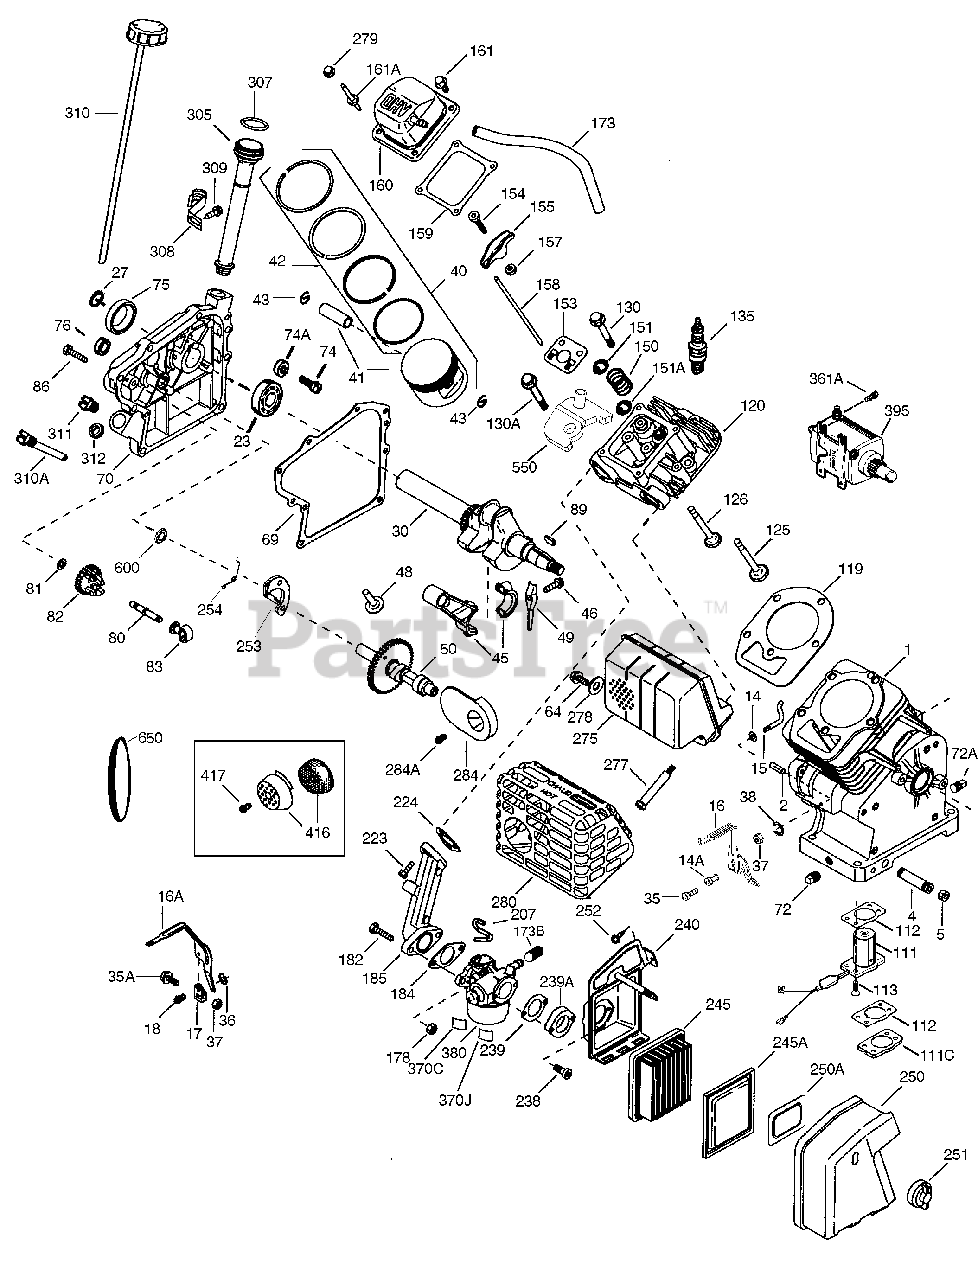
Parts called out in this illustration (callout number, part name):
1	"order short block or engine no longer available
2	Dowel Pin
15	Governor Rod (Incl. 38)
16	Governor Lever
23	Ball Bearing
27	Bearing Retainer Ring
30	Crankshaft
35	Screw, 10-32 x 63/64"
37	Square Nut
38	Retaining Ring
40	Piston, Pin & Ring Set (Std.)
40	Piston, Pin & Ring Set (.010" OS)
42	Ring Set (Std.)
42	Ring Set (.010" OS)
43	Piston Pin Retaining Ring
45	Connecting Rod Ass'y (Incl. 46 & 49)
46	Connecting Rod Bolt
48	Valve Lifter
49	Oil Dipper
50	Camshaft (Incl. 150, 253 & 254)
64	Screw, 1/4-20 x 1-1/8"
69	* Cylinder Cover Gasket
70	Cylinder Cover (Incl. 75 thru 83 & 31 1)
72	Oil Drain Plug (Sq. hd., 1/4-18)
72A	Oil Drain Plug (Sq. hd., 1/4-18)
75	Oil Seal
80	Governor Shaft
82	Governor Gear Assembly (Incl. 81)
83	Governor Spool
86	Screw, 1/4-20 x 1-1/4"
89	Flywheel Key (also available in Packa ged Part #740007B)
119	* Cylinder Head Gasket
120	Cylinder Head (Incl. 151A)
125	Exhaust Valve (Std.) (Incl. 151)
125	Exhaust Valve (1/32" OS) (Incl. 151)
126	Intake Valve (Std.) (Incl. 151 & 151A )
130	Screw, 5/16-18 x 1-1/2"
130A	Screw, 5/16-18 x 2-41/64"
135	Resistor Spark Plug (RN4C) also avail able in Packaged Part #740069
150	Valve Spring
151	Valve Spring Cap
151A	Valve Seal
153	Push Rod Guide
154	Rocker Arm Stud
155	Rocker Arm
157	Nut, 1/4-28
158	Push Rod
159	* Rocker Arm Cover Gasket
160	Rocker Arm Cover
173	Breather Tube
182	Screw, 1/4-20 x 1"
184	* Carburetor To Intake Pipe Gasket
185	Intake Pipe
207	Throttle Link
224	* Intake Pipe Gasket
229	Nut & Lock Washer
238	Screw, 10-32 x 1/2"
239	* Air Cleaner Gasket
240	Air Cleaner Body (Incl. 239)
245	Air Filter (Paper) (also available in Packaged Part #740031B for model VLV only) (also available in Packaged Pa rt #740061C for model OH195)
245A	Poly Pre-Filter (also available in Pa ckaged Part #740061C)
250	Air Filter Cover (Incl. 250A)
250A	Air Filter Baffle
251	Wing Nut
253	Compression Release Weight
254	Compression Release Spring
275	Muffler Carburetor Side Discharge
277	Screw, 1/4-20 x 2-9/32"
280	Heat Shield
309	Screw, 10-32 x 5/16"
310A	Oil Gauge Ass'y.
311	Oil Fill Plug (Incl. 312) also availa ble in Packaged Part #740079
312	Oil Fill Plug Gasket
338	Screw, 10-32 x 1/2"
365	Screw, 8-32 X 27/64``
370	Decal - Tecumseh Logo for Top of Reco il Starter
370	Decal - Choke Lever - Off/Full
370	Decal - Low Oil Sentinel - Set of Lig ht & Switch Information
380	Carburetor (Incl. 184)
416	Spark Arrestor Kit (Incl. 417) Option al
701	Screw, 1/4-20 x 31/64"
999	Summer Maintenance Kit (incl. Oil, Sp ark Plug, Air Cleaner, & Ultra Fresh)
